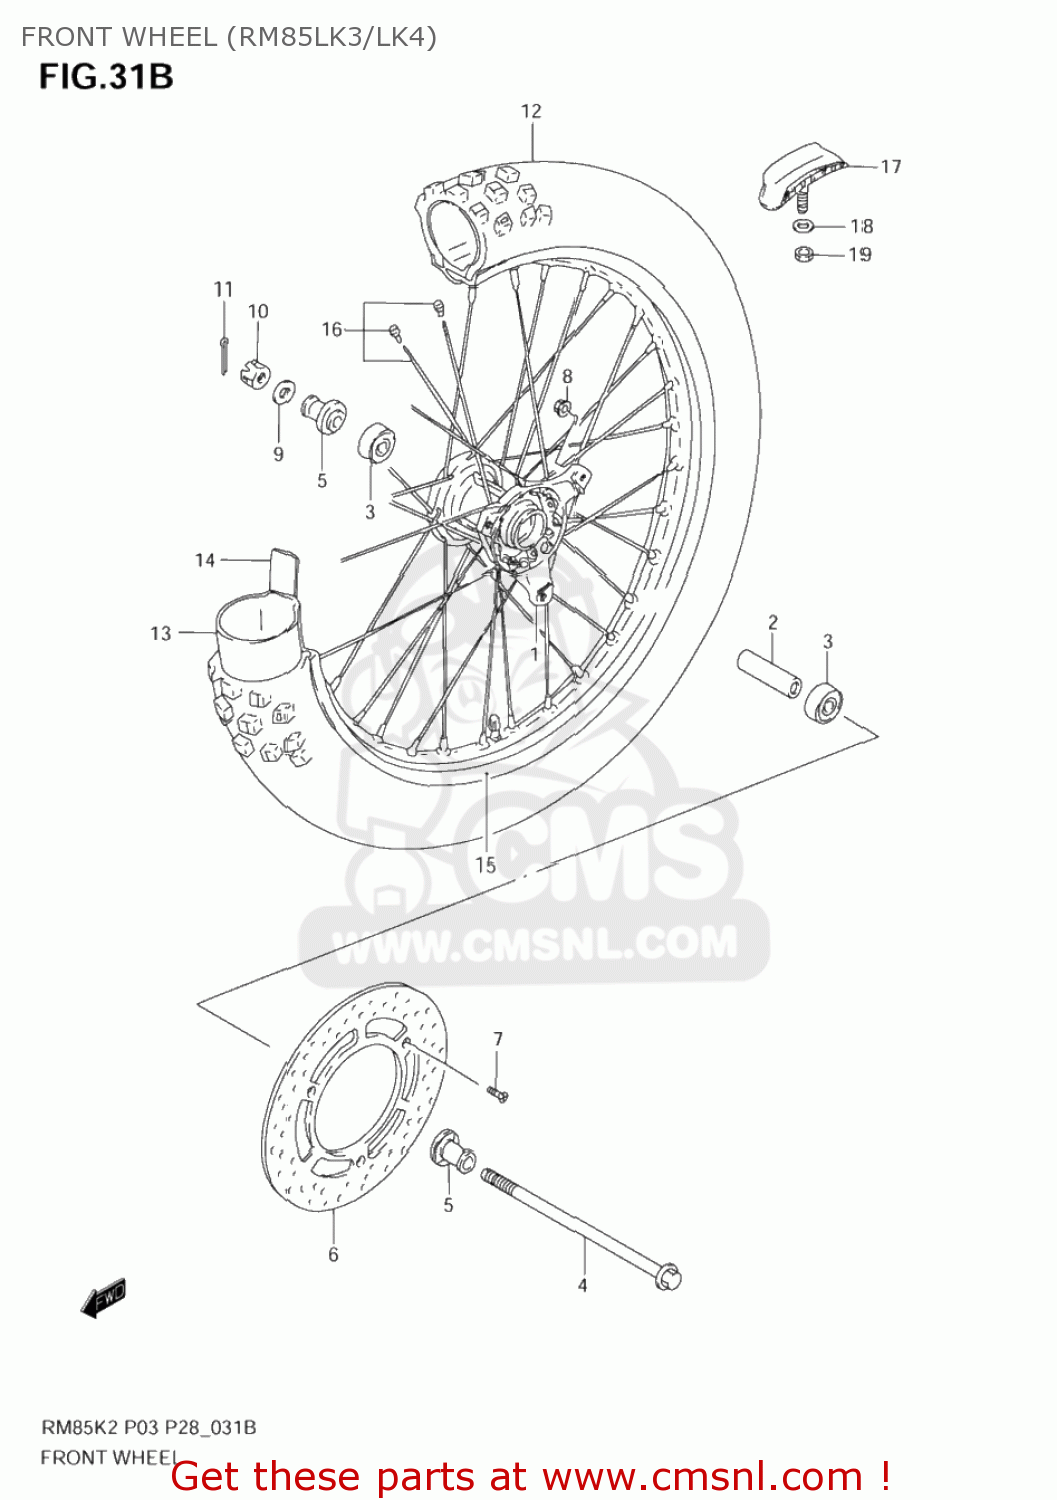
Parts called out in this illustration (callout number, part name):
1	HUB,FR WHEEL
2	SPACER,FR HUB BEARING
3	BEARING (12X32X10)
4	AXLE,FR
5	SPACER,FR AXLE
6	DISC,FRONT BRAKE
7	SCREW(6X22)
8	NUT
9	WASHER
10	NUT,M12X1.25X1
11	PIN 20X20
12	TIRE,FR(70/100 19 42M D737F)
13	TUBE ASSY,WHEEL INNER
14	PROTECTOR,WHL INR TUBE
15	RIM,FR WHEEL(1.40X19)
16	SPOKE SET,FR WHEEL
17	STOPPER,BEAD
18	WASHER
19	NUT
